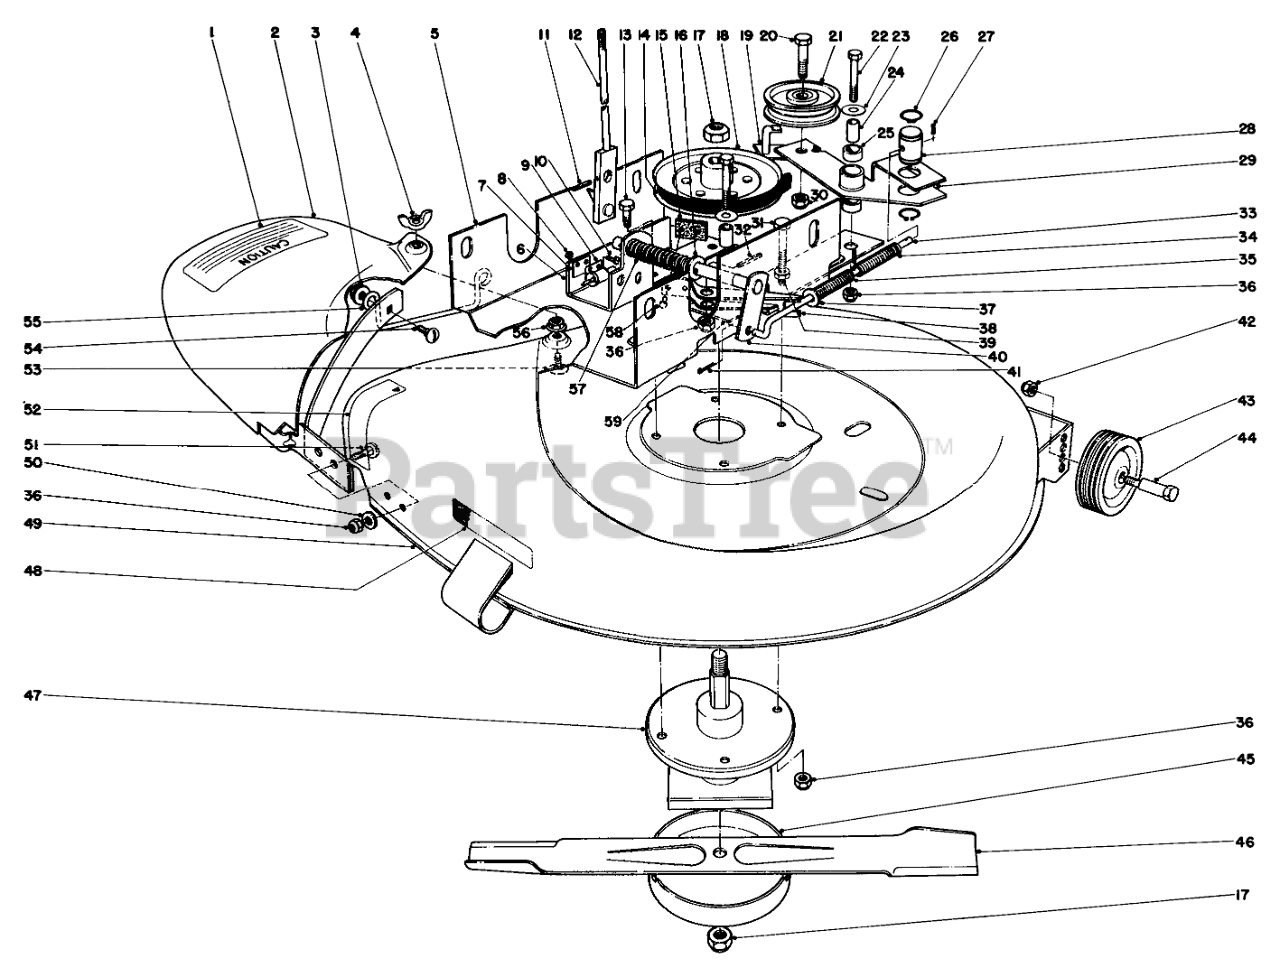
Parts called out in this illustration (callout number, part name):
1	Decal
2	DEFLECTOR WA R
3	NUT-LOCK, HHF
4	Wing Nut
5	CHANNEL HT ADJ R
6	50 Mounting Bracket Blade
7	Spacer Switch
8	NUT-KEPS
9	Switch-Interlock
11	PIN-SPIRAL
12	Lever Deck Engagement
13	Screw
14	V-BELT
15	BLADE BRAKE LINING
16	WASHER-FLAT
18	DECK PULLEY R
19	Belt Retainer
20	SCREW-HH
21	Flat Idler
22	SCREW-HH
23	WASHER-PLAIN
24	PIVOT SPACER
25	Bushing
26	RING-RETAINING
27	PIN-ROLL
28	Pin-Pivot
29	Idler Arm (Incl. Ref. #25)
30	NUT-LOCK, CONE
31	SCREW-HH
32	PIN-SPRING
33	BLADE ENGAGE ROD
34	Spring Deck Idler
35	Spring Deck Brake
36	NUT-LOCK, CONE
37	WASHER
38	Blade Brake (Incl. Ref. 15 & 58)
39	NUT-JAM
40	Linkage
41	PIN-COTTER
42	Nut
43	Wheel
45	Cup
46	Blade
47	Mower Spindle
48	Decal-Deck Inst.
49	HOUSING WA R
50	WASHER-FLAT
51	BOLT-CARR
52	Decal Housing
53	Carriage Bolt
54	SCREW-CARRIAGE
55	Bracket Foot Guard
56	PAL NUT
57	COMP SPRING O
58	Rivet
59	Bracket Idler Mounting
